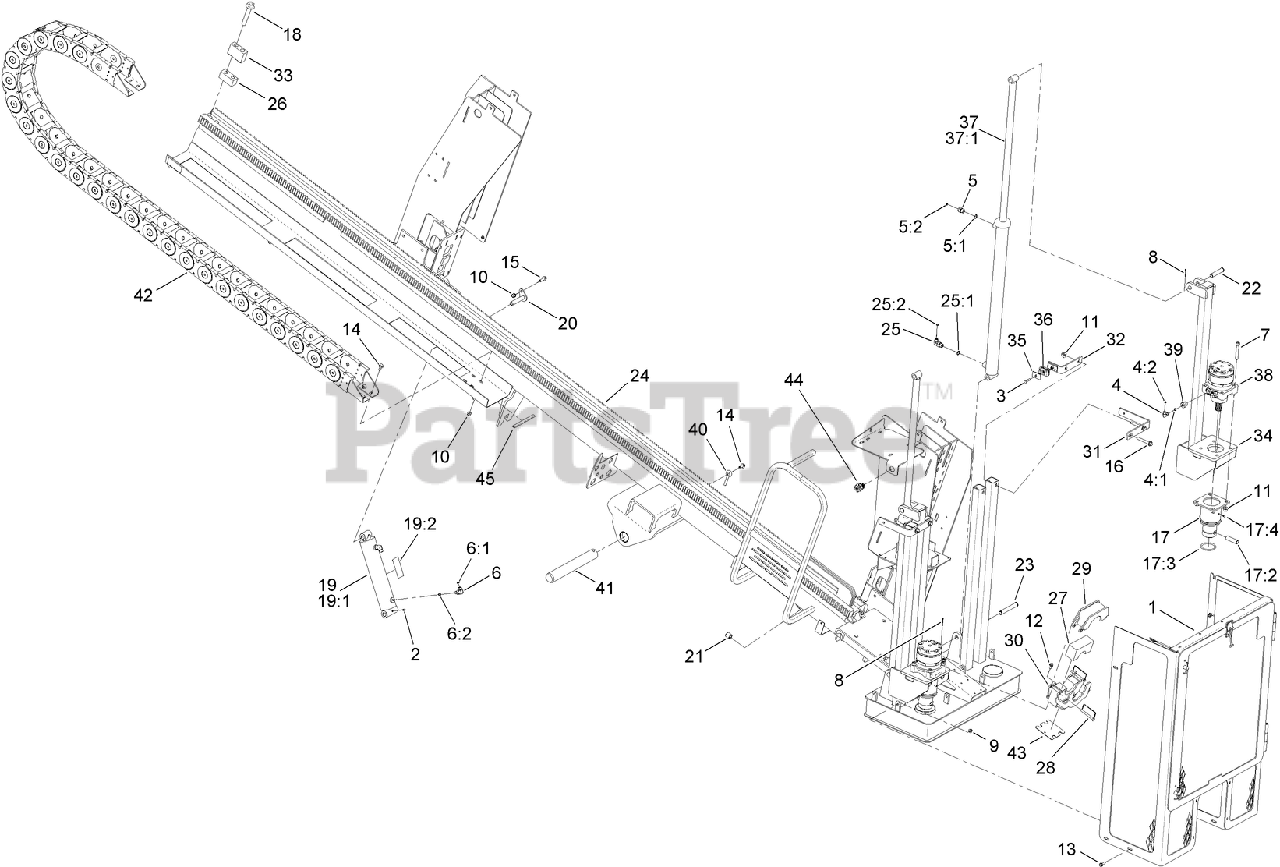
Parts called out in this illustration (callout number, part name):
1	STAKEDOWN CAGE ASM
2	FITTING-GREASE
3	SCREW-HH
4	FITTING-90 DEG
4:1	O-RING
4:2	O-RING
5	FITTING-STR
5:1	O-RING
5:2	O-RING
6	FITTING-ELBOW, 90 DEG
6:1	O-RING
6:2	O-RING
7	SCREW-HSH
8	PIN-COTTER
9	NUT-LOCK, HHF
10	NUT-LOCK, NI
11	NUT-LOCK, HHF
12	SCREW-HHF
13	SCREW-HHF
14	SCREW-HHF
15	SCREW-HHF
16	SCREW-HHF
17	STAKEDOWN COUPLER ASM
17:2	PIN-COUPLING, STAKE
17:3	O-RING
17:4	FITTING-GREASE
18	SCREW-HHF
19	LIFT CYLINDER ASM
19:1	Cylinder-Hydraulic
19:2	DECAL-CAUTION, CYLINDER LOCK
20	PIN-FLAG
21	BUSHING-SPRING
22	PIN-CLEVIS
23	PIN-CLEVIS
24	THRUST FRAME ASM
25	FITTING-ELBOW 90
25:1	O-RING
25:2	O-RING
26	BLOCK-TAPPED
27	GUIDE-ROD, BUSHING
28	PIN-SELF LOCKING
29	GUIDE-ROD BUSHING, TOP
30	GUIDE-ROD BUSHING, BOTTOM
31	TIE-POST, STAKEDOWN
32	TIE-POST, HOSE BRACKET
33	STOP-CARRIAGE
34	STAKEDOWN
35	PLATE-COVER, TWIN
36	CLAMP-HALF (SET OF 2)
37	HYD CYLINDER ASM
38	HYD MOTOR ASM
39	REDUCER-STRAIGHT, THREADED
40	PIN-RETAINER
41	PIN-PIVOT, THRUST FRAME
42	CARRIER-HOSE
43	SHIM-ROD GUIDE, BOTTOM
44	RECEPTACLE-12V
45	TRIM-CARRIER, HOSE
